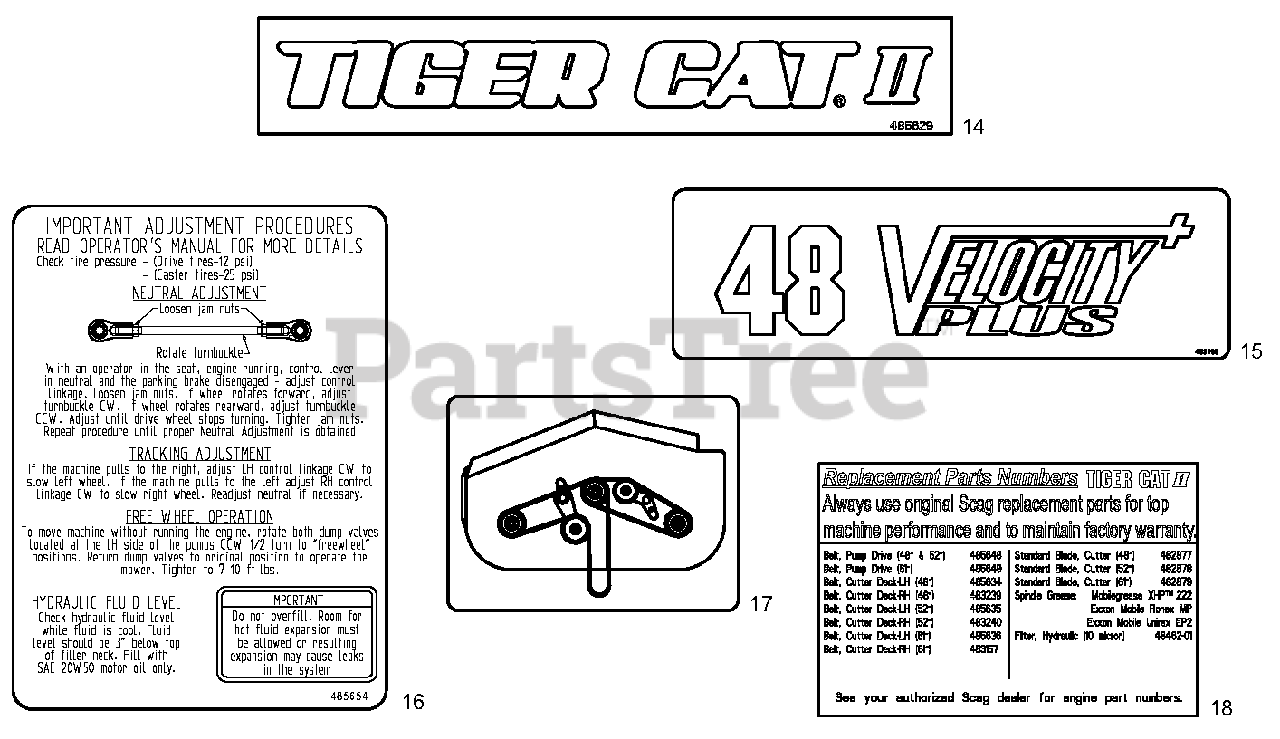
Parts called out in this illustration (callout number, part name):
14	Decal, Tiger CatII
15	Decal, 48V
15	Decal, 52V
15	Decal, 61V
16	Decal, Seat Support
17	Decal, Belt Routing (48V & 52V)
17	Decal, Belt Routing (61V)
18	Decal, STCII Replacement Parts
